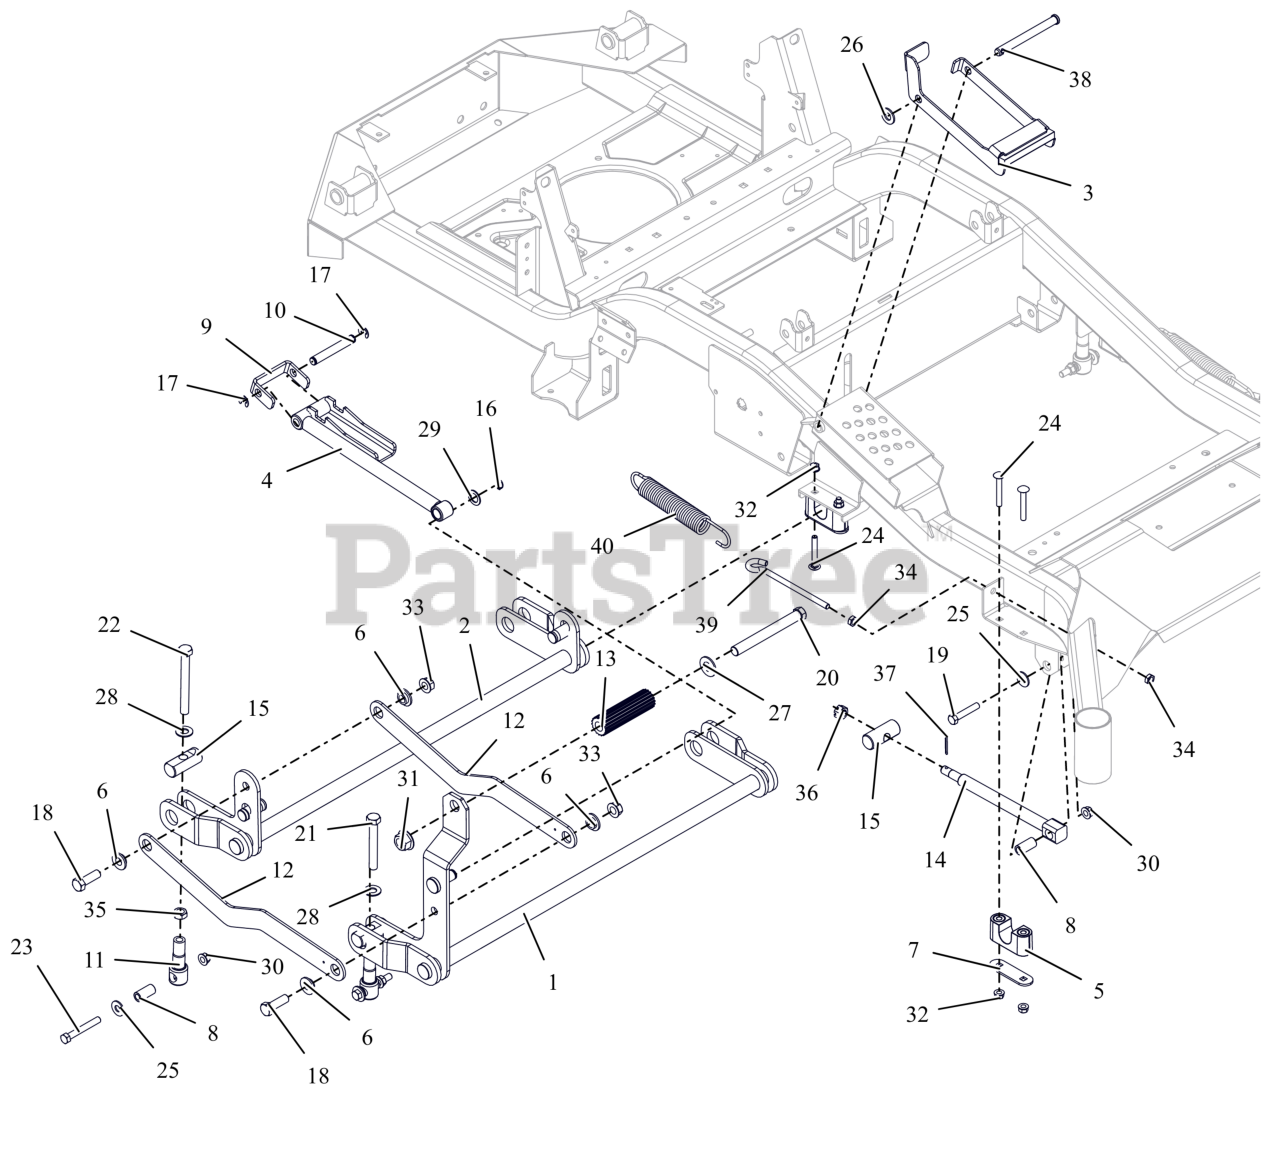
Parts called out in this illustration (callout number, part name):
1	WLDMT, FRONT DECK LIFT PIVOT
2	WLDMT, REAR DECK LIFT PIVOT
3	BRKT, HOC TRANSFER LOCK
4	WLDMT, HOC ARM
5	ASM-BUSHING, DECK LIFT
6	BSHG-FLG .515X.750X.395X1.120
7	PLATE, BEARING SUPPORT
8	SPACER, DECK LEVELING
9	BRKT, HOC LINE
10	ROD, HOC PIVOT
11	LINK, DECK LIFT FORMED
12	LINK, DECK LIFT
13	ROD, FOOT PEDAL (BLACK)
14	DRAG,LINK-HD
15	PIN, DECK LIFT
16	RG-RTNG-EXT .625X.050
17	RG-RTNG-EXT .500X.042 (E)
18	BLT,HEX .50-13X1.50 G5 ZCC
19	BLT,HEX .38-16X2.00 G5 ZCC
20	BLT, HEX .62-11X5.50 G5 FBP
21	BLT, HEX .50-13X3.50F G5 ZCC
22	BLT, HEX .50-13X4.50F G8 ZCC
23	BLT, HEX .38-16X2.75 G8 ZCC
24	BLT, RHSSN.31-18X2.25 G5 ZCC
25	WSHR,FLT .438X1.00X.083 ZCC
26	WSHR,FLT .531X1.062X.095 ZCC
27	WSHRFLT 5/8SAE CARBHARD FBP
28	WSHR, FLT .557X1.040X.102 ZCC
29	WSHR, FLT .630X1.005X.062 ZCC
30	NUT-LK-TOP-FLG .38-16 ZC120
31	NUT,FLG-TOP LK .625-11 FBP
32	NUT,LK-CTR-FLG .31-18 GF ZCC
33	NUT-LK-TOP-FLG .500-13 GF ZCC
34	NUT-JAM .375-16 G2 ZCC
35	NUT-JAM .500-13 G2 ZCC
36	NUT-SL .50-13
37	PIN,CTR.12X1.25EXTPRSQCT ZC120
38	PIN-SLIC .50X4.97X4.55 -ZCC
39	BOLT,.38-16 X 5.25-.62 DIA EYE
40	SG-TENS .162X1.25X8.25 WLD 25
